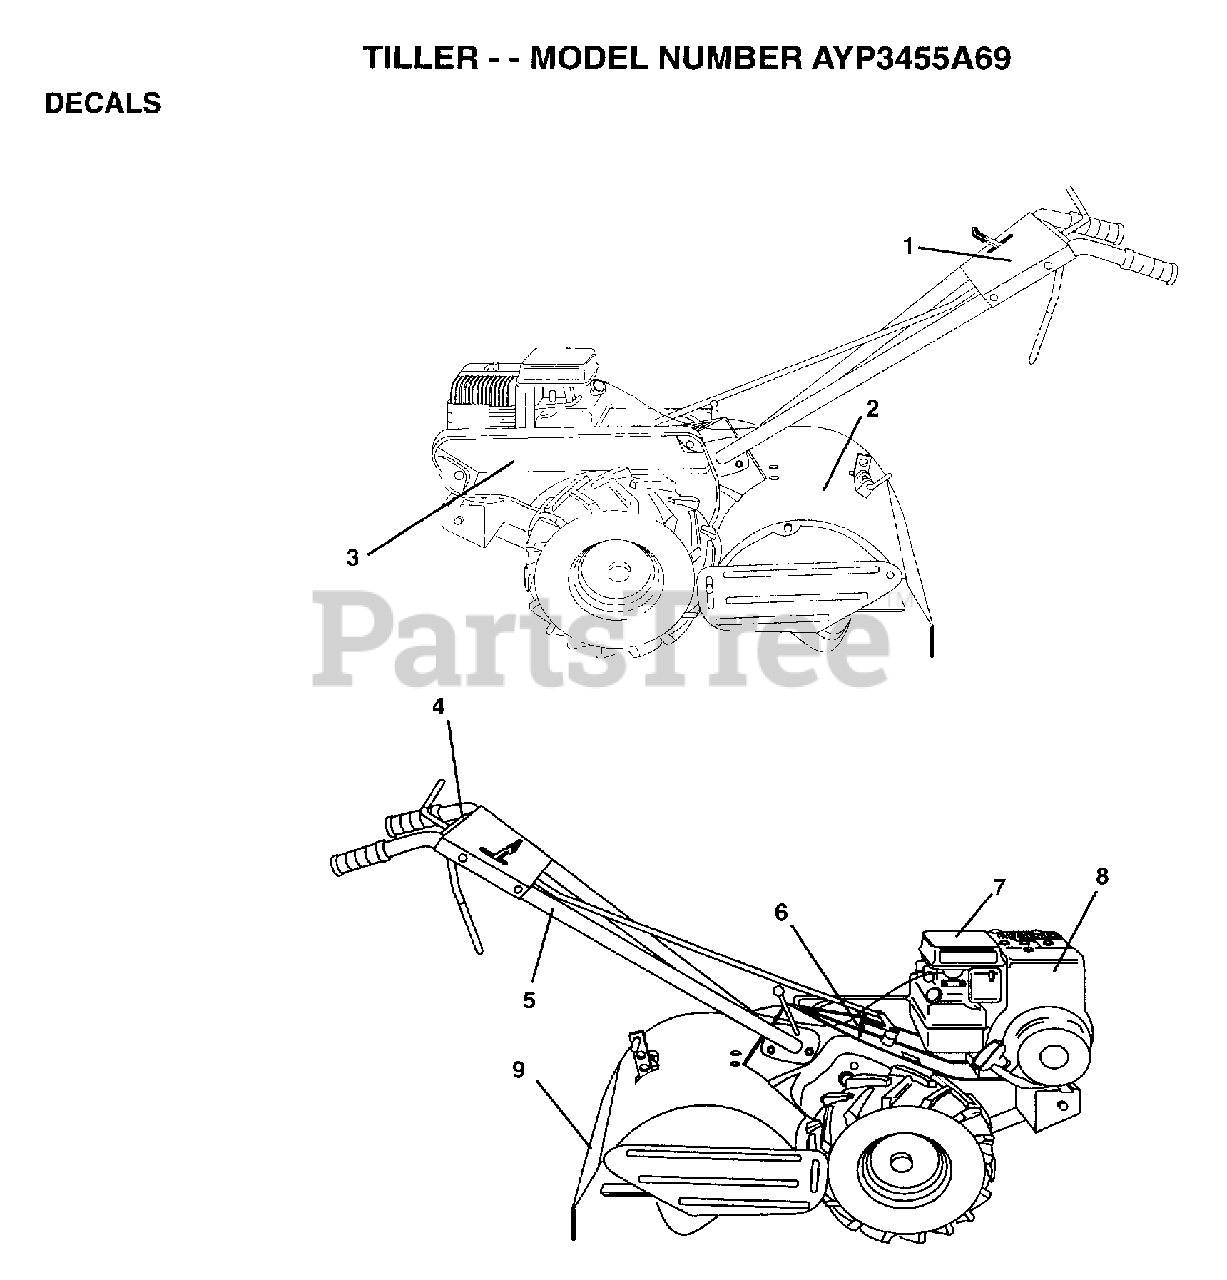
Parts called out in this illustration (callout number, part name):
1	DECAL.CNTRL.PNL.W
3	DECAL.GUARD.BLT.W
5	DECAL TI
6	DECAL CRT
8	DECAL, BRIGGS & STRATTON
9	DECAL TI
